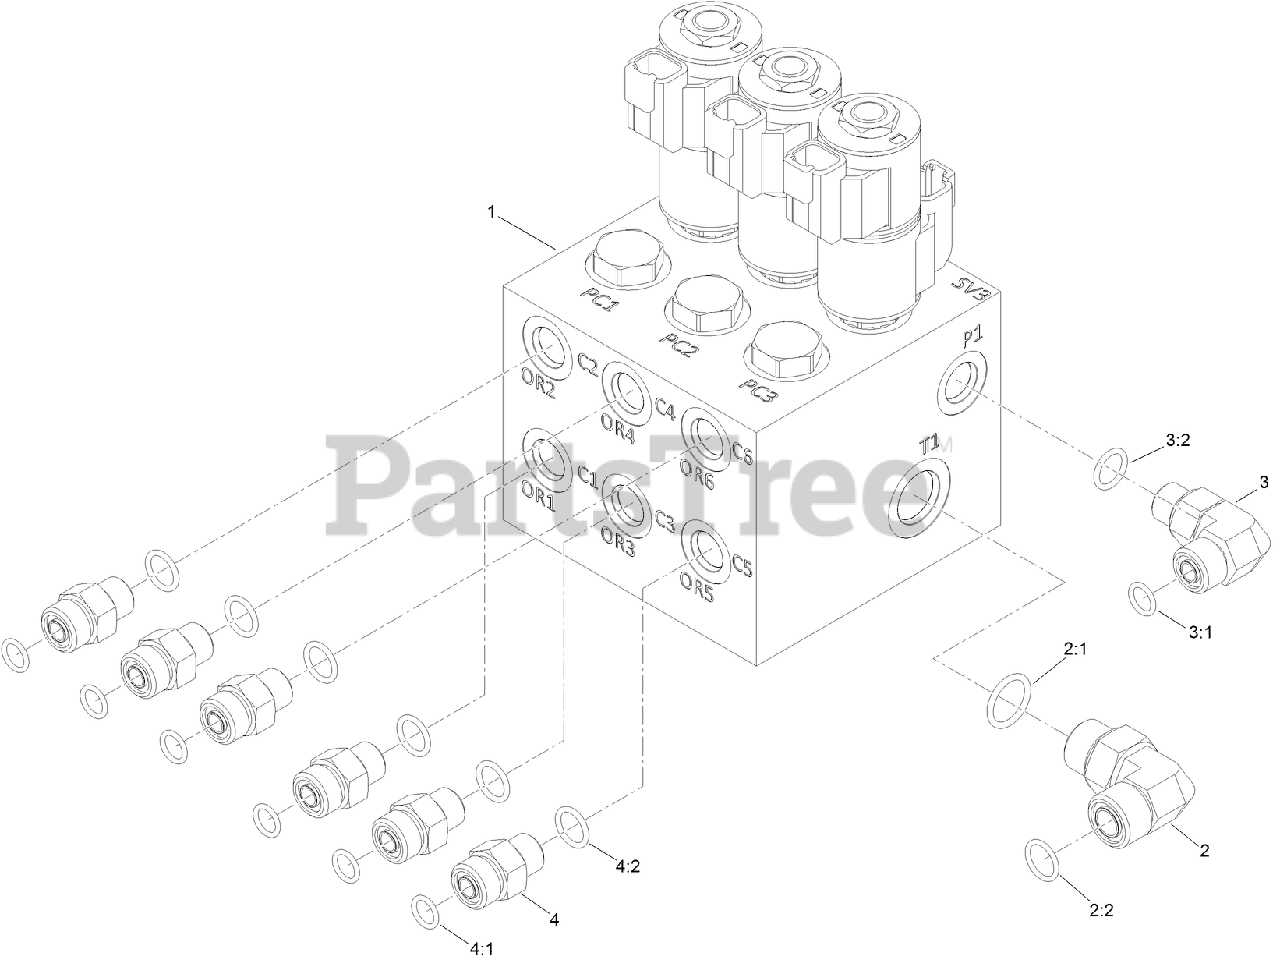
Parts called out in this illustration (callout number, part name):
1	SETUP MANIFOLD ASM
2	FITTING-ELBOW, 90 DEG
2:1	O-RING
2:2	O-RING
3	FITTING-ELBOW, 90 DEG
3:1	O-RING
3:2	O-RING
4	FITTING-STRAIGHT
4:1	O-RING
4:2	O-RING
